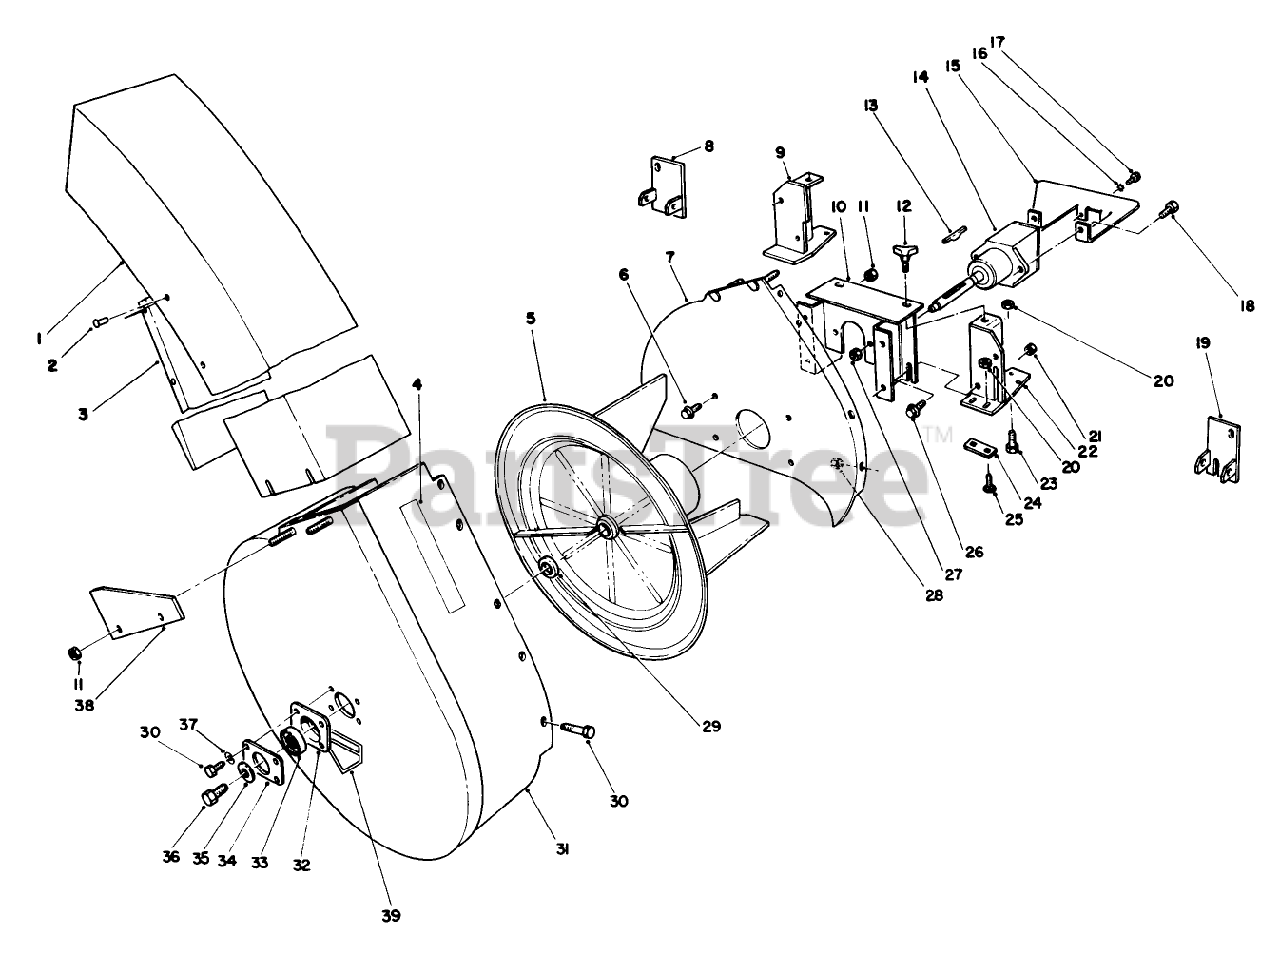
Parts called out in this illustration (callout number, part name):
1	Chute Assembly (Incl. Ref. #2 & 3)
3	Deflector
4	Decal-Waming
5	Impeller
6	SCREW-HHF
7	Mounting Plate
8	Bracket-Deflector L.H.
9	LH BRACKET ASM
10	Blower Mount
11	NUT-LOCK, NI
14	Asm-Gear Box
15	Cover-Gear Box
16	WASHER-LOCK, EXT
18	SCREW-HH
19	Bracket-Deflector R.H.
20	NUT-LOCK, CONE
21	NUT-JAM
22	RH BRACKET ASM
23	SCREW-HH
24	Plate-Bracket
25	BOLT-CARR
26	SCREW-HHF
27	NUT-LOCK, NI
28	NUT-LOCK, NI
29	SPACER-BEARING
30	SCREW-HH
31	BLOWER HOUSING ASM
32	CUP-BEARING
33	BEARING-BALL
34	Cover-Plate
35	SPACER
36	SCREW-HH, LOCK
37	WASHER-LOCK
38	Bracket
39	DECAL-DANGER
